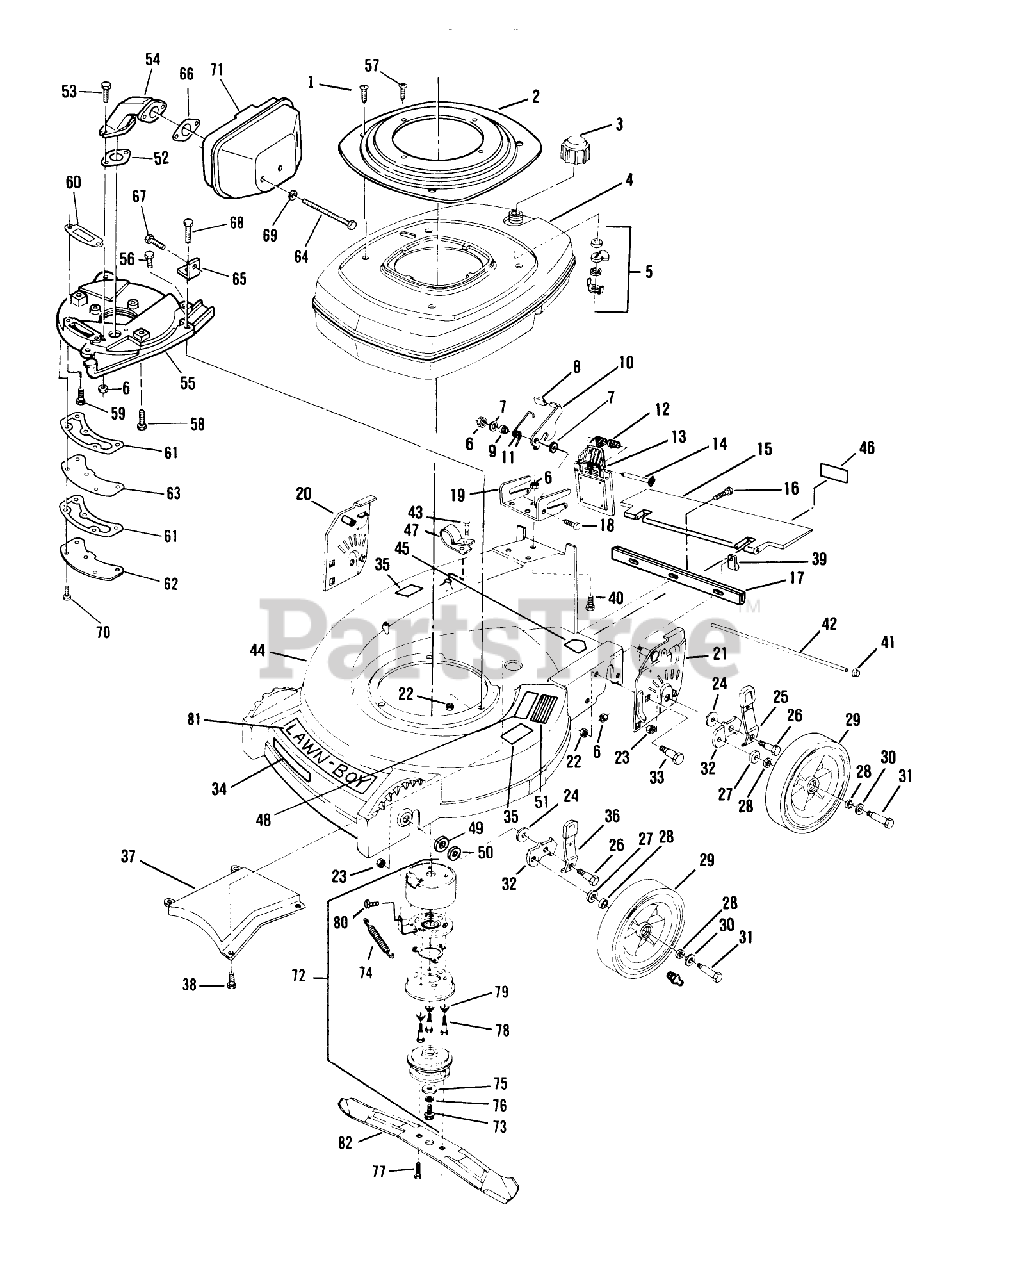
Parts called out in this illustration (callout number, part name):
3	FUEL CAP & INSERT
5	SHUT-OFF VALVE S
6	LOCKNUT E
8	KNOB (S&R)
11	SPRING
12	SPRING ASOC
14	ROD (RB&W)
15	T/SHIELD SM&P
22	NUT-LOCK F
23	LOCKNUT
24	WASHER
26	BOLT
27	WASHER WROUGHT
28	WASHER
30	SPACER
31	BOLT WHEEL
36	SPRING ARM ASM
37	BAFFLE CHUTE PL
43	SCREW LAWRENCE
49	WASHER
50	WASHER
51	PAD FOOT
56	SCREW
57	SCREW SEMS SM
58	SCREW V
61	GASKET S
62	COVER HIP
66	GASKET S
67	SCREW-SEMS
68	SCREW
74	SPRING
75	WASHER
77	SCREW SEMS
78	SCREW,SHOULDER SM
